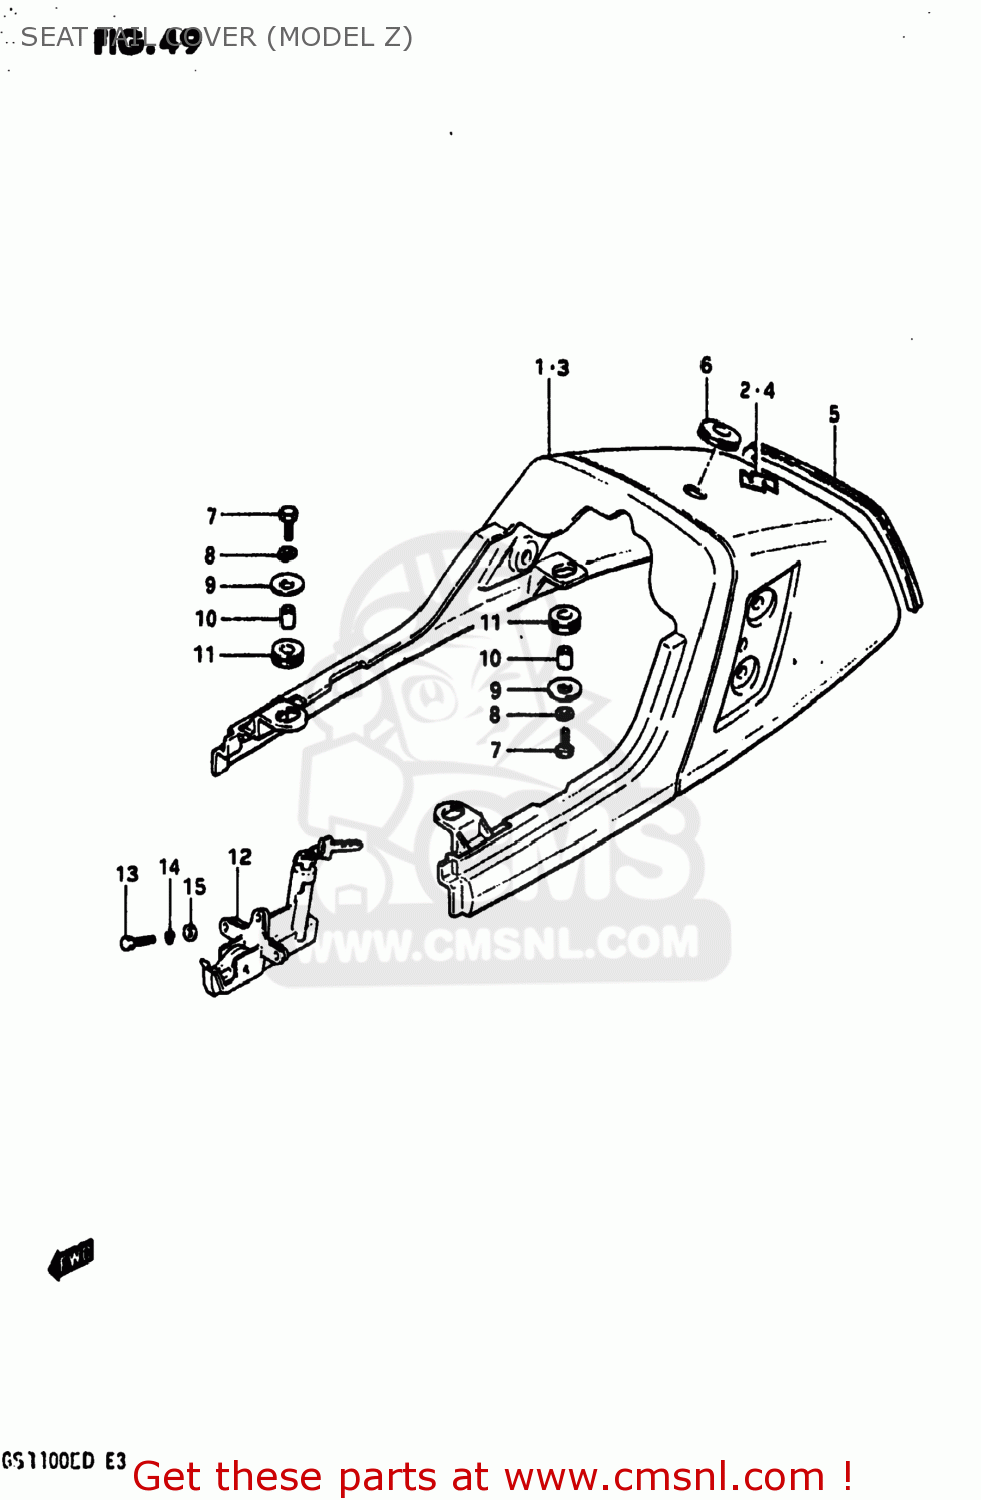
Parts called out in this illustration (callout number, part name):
1	COVER,SEAT TAIL
2	EMBLEM (S)
3	COVER,SEAT TAIL
4	EMBLEM (S)
5	RUBBER,BLIND,SEAT TAIL COVER
6	GROMMET,SEAT LOCK HOLE
7	BOLT
8	LOCK WASHER
9	WASHER(6,5X22X1.6)
10	SPACER(6.5X10.5X12)
11	CUSHION
12	LOCK SET,SEAT
13	BOLT
14	LOCK WASHER
15	WASHER
